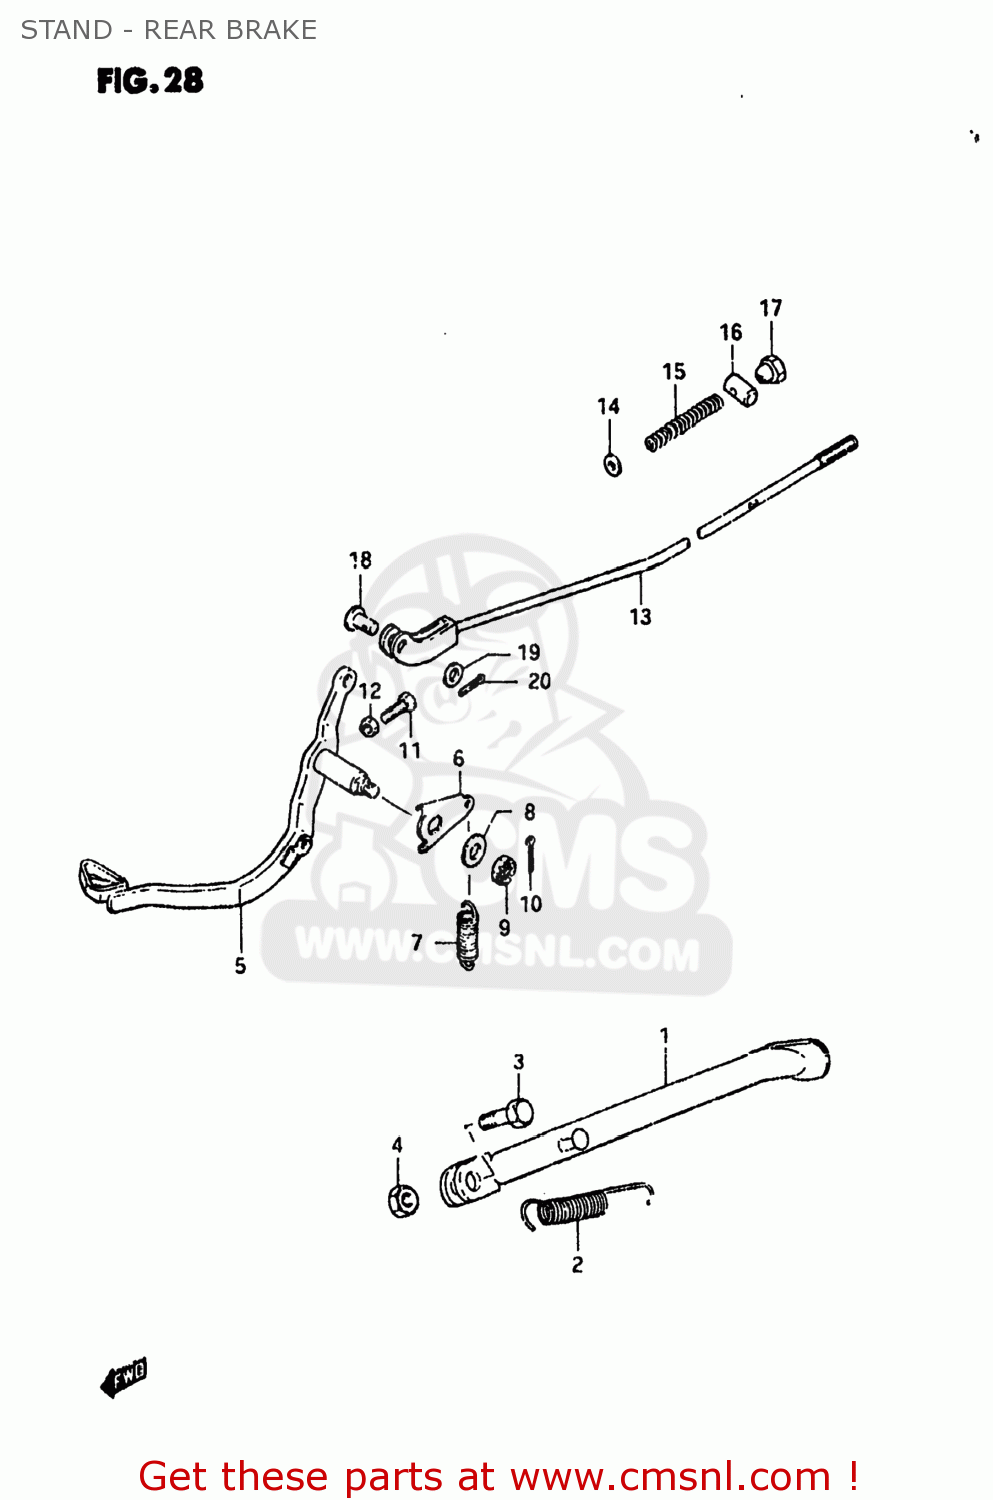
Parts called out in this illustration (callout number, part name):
1	STAND,SIDE
2	SPRING
3	BOLT(10X30)
4	NUT
5	PEDAL,BRAKE
6	ARM,BRAKE RETURN SPRING
7	SPRING
8	WASHER
9	NUT 8MM
10	PIN 20X20
11	BOLT(6X23)
12	NUT
13	ROD ASSEMBLY,REAR BRAKE
14	WASHER
15	SPRING
16	PIN(11X18)
17	NUT
18	PIN
19	WASHER
20	PIN 20X20
